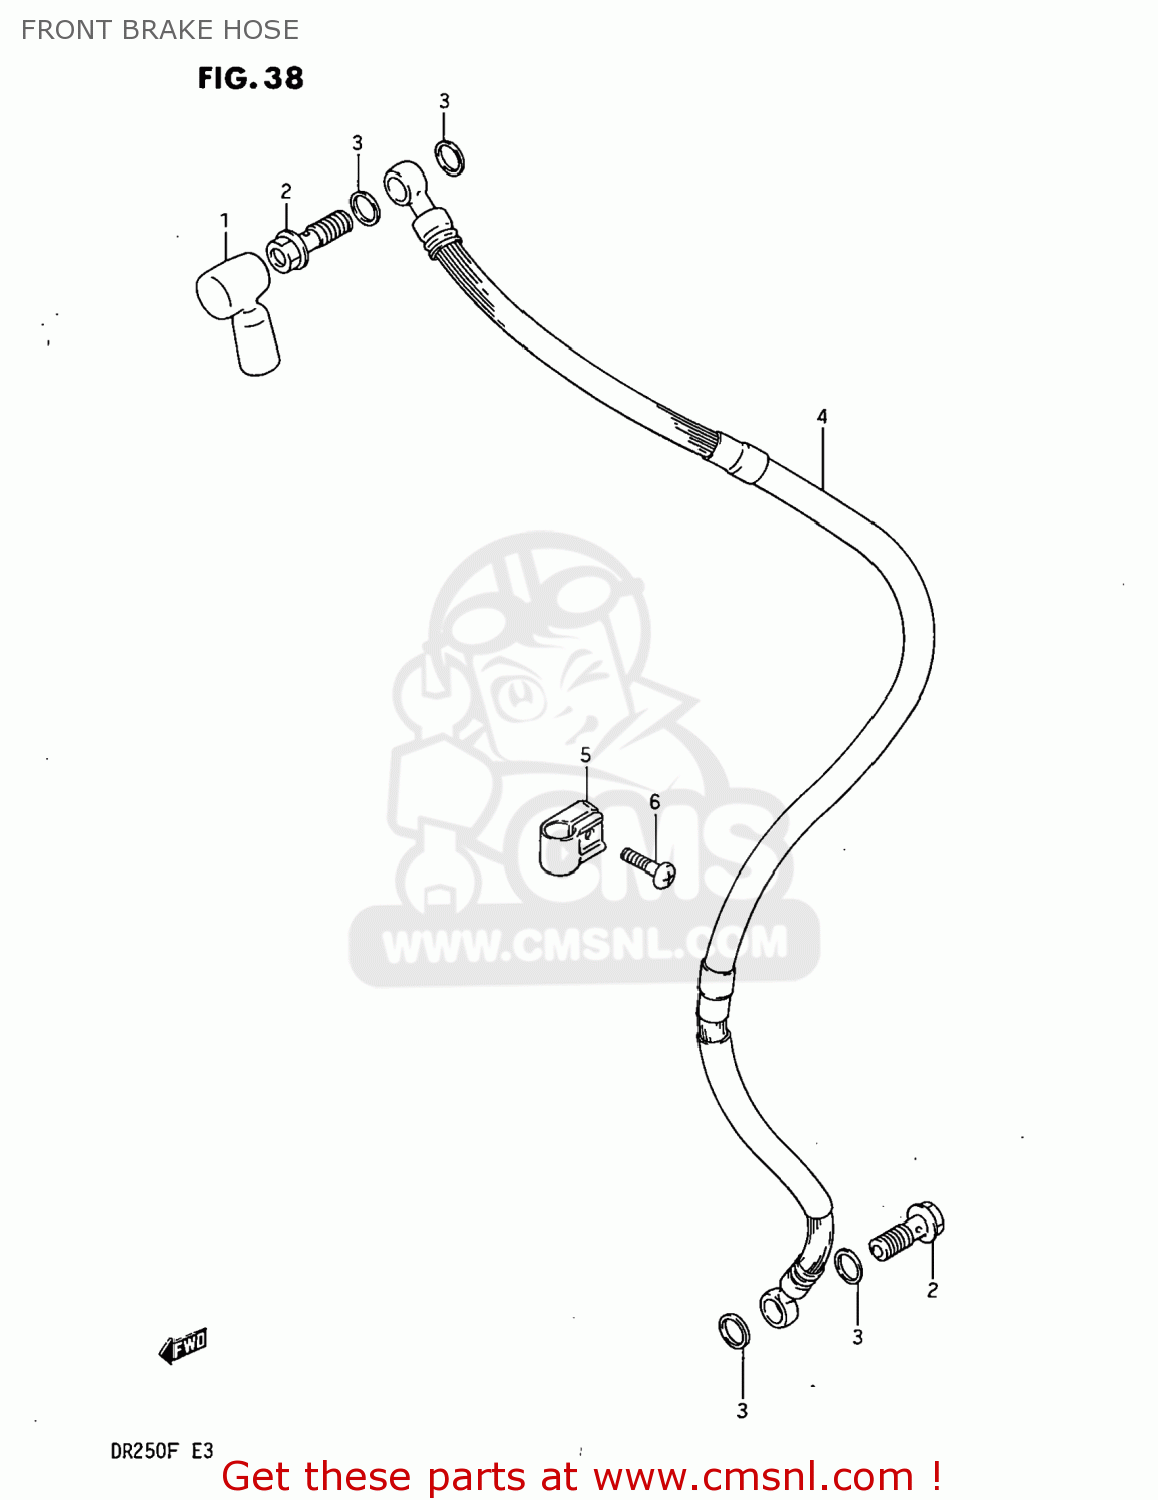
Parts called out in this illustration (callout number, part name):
1	BOOT,MASTER CYLINDER
2	BOLT UNION
3	WASHER(10X15X1.5)
4	HOSE,FRONT BRAKE
5	CLAMP,BRAKE HOSE
6	SCREW
